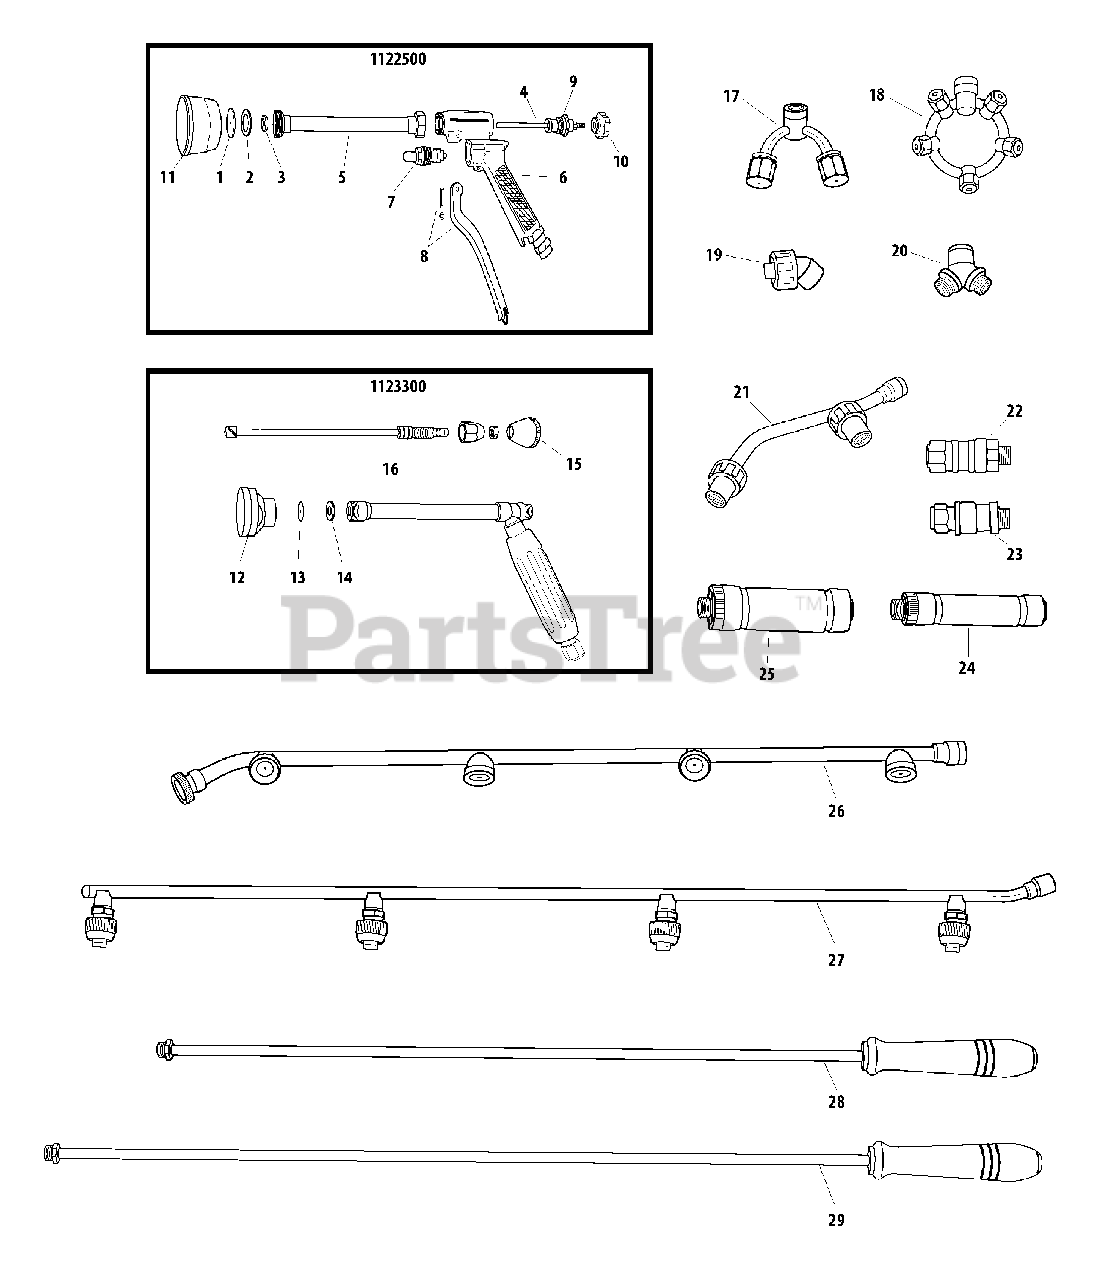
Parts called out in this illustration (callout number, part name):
1	PLATE, NOZZLE
2	O-RING
3	SWIRL CORE
4	CENTER SHAFT ASSY
5	TUBE
6	VALVE GRIP ASSY
7	VALVE ASSY
8	LEVEL ASSY
9	SEAL ASSY
11	CAP, NOZZLE
12	CAP, NOZZLE
13	PLATE, NOZZLE
14	O-RING
15	KNOB
16	CENTER SHAFT ASSY
17	NOZZLE ASSY
18	NOZZLE ASSY
19	NOZZLE ASSY
20	ADAPTOR
21	NOZZLE ASSY
22	SWIVEL, CONNECTOR
23	SWIVEL
24	FILTER, FUEL
25	FILTER, FLUID - HEAVY DUTY
26	SPRAY WAND ASSY
27	SPRAY WAND ASSY
28	WAND - 680mm
29	WAND - 890mm
1122500	SPRAY GUN, PAL
1123300	SPRAY NOZZLE, C2
